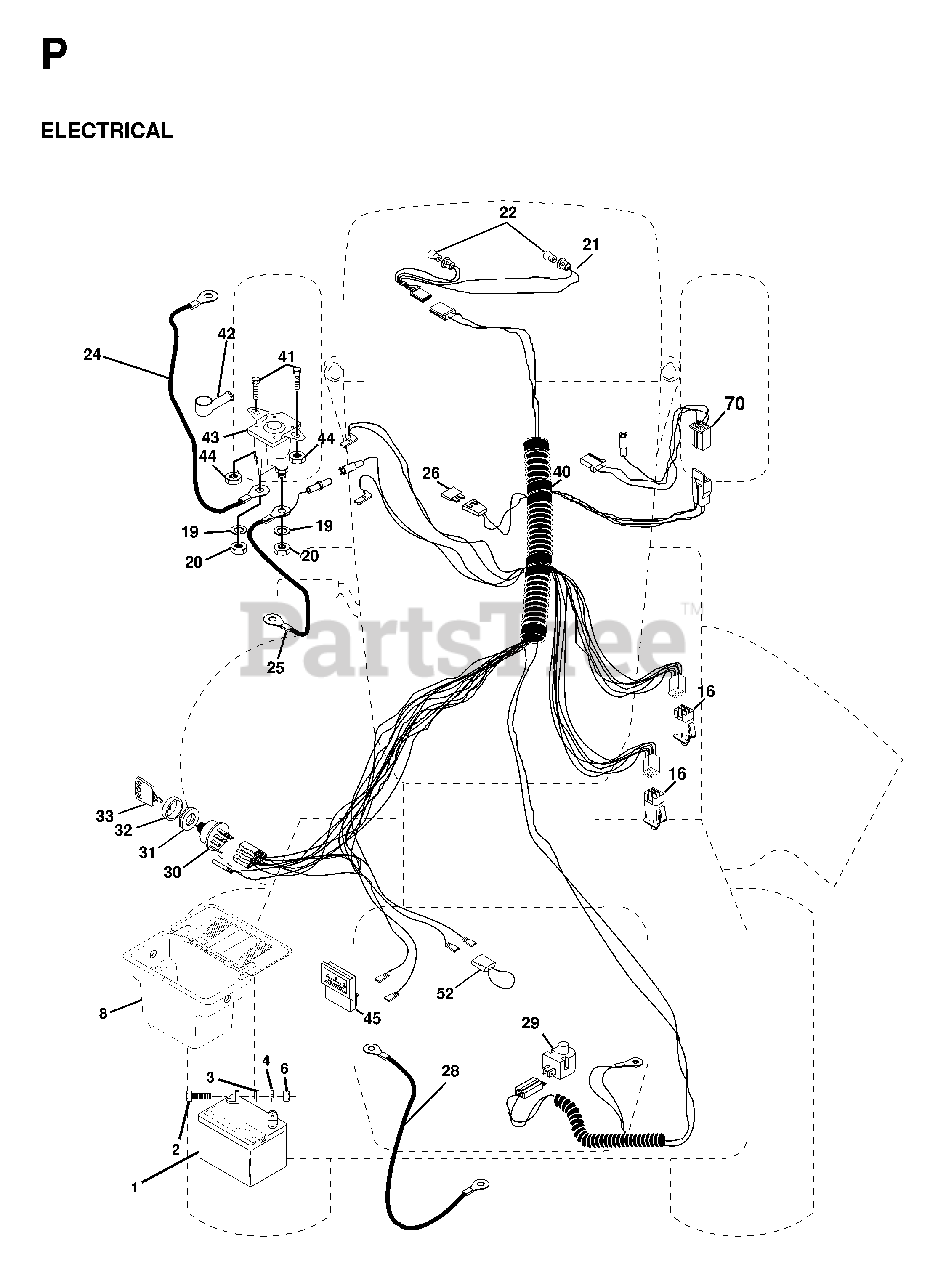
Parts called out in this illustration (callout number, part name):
1	BATTERY 12 VOLT 25 AMP
3	WASHER
4	LOCKWASHER
6	NUT
8	CASE BATTERY MECH HINGE
16	SWITCH INTERLOCK
19	LOCKWASHER
20	NUT
21	HARNESS ASM HDLIG
22	LIGHTBULB
24	BATTERY CABLE GT
25	CABLE BATTERY
28	CABLE T
29	SWITCH SEAT
30	SWITCH.IGNITION.4.POSITION
31	NUT IGNITION
32	COVER SWITCH KEY
40	HARNESS IGN
42	TERMINAL COVER
43	SOLINOID
52	WIRE PROTECTION LOOP
70	HARNESS, ENGINE
